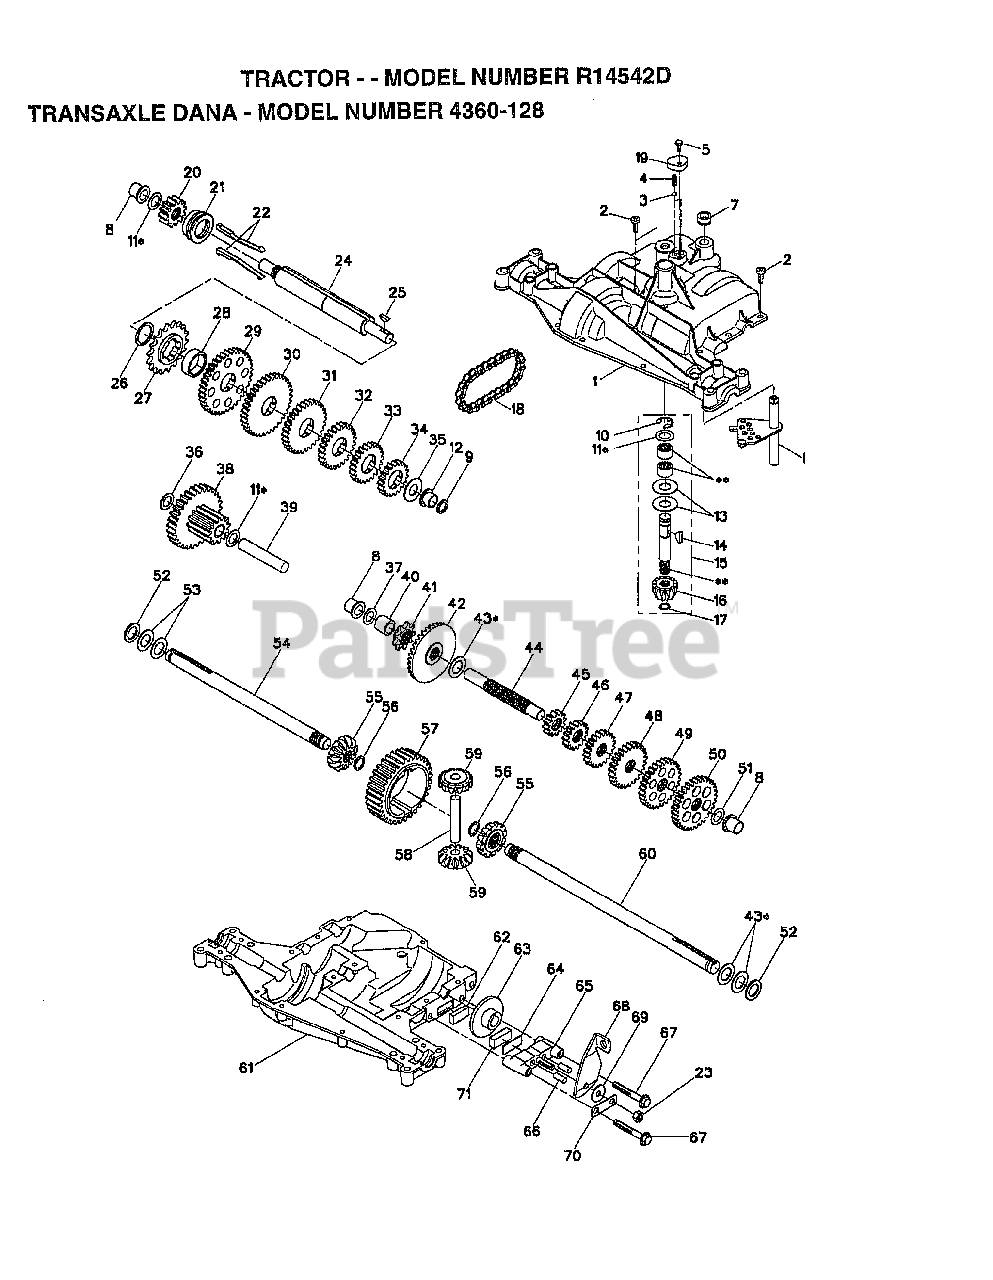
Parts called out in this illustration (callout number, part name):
1	HOUSING.UPPER(5305-P)
4	"SPRING, DETENT LT"
5	SCREW.TAPPING.1/4-20X.734
6	KIT SHIFTER ASM
9	SEAL.OIL.DAN.5508
10	RETAINING RING LT
11	ASM KIT SHIM 4689
12	BEARING.FLNG.5511
13	WASHER T
14	KEY WOODRUFF-DANA
15	INPUT SHAFT KIT 6250
16	PINION.BEVEL.12T(5620)
17	"RING,RETAINING LT"
18	"CHAIN,24 PTCH LT"
19	COVER.DETENT.(5584)
20	GEAR.SPUR.12T.(5627)
21	CLUTCH.COL.5467
22	ASM KIT CLTCH KEY
23	NUT.LOCK.5/16-24
24	SHAFT INTERM DANA
25	WOODRUFF KEY
26	"RING,RETAINING LT"
27	SPROCKET 18T T
28	SPACER YT
29	GEAR SPUR 37 TTH
30	GEAR SPUR 35 TTH
31	GEAR SPUR 30T
32	GEAR 25T LT
33	GEAR SPUR 22 TT
34	SPUR GEAR 19T
35	"WASHER, PLAIN LT"
36	WASHER 045
37	WASHER 031
38	ASSY.GEAR.6153 12T&30T
39	SHAFT IDLER
40	SPACER T
41	SPROCKET 9T LT
42	GEAR.BEVEL.36T(5621)
43	ASM KIT SHIM
44	SHAFT T
45	GEAR SPUR 12 TTH
47	GEAR SPUR 20T
48	"GEAR, SPUR 25T LT"
49	GEAR 28T T
50	"GEAR, SPUR 31T LT"
51	WASHER 060
52	NEOPRENE WASHER
53	WASHER 031
54	AXLE.LH(5528-1)
55	MITER 5270 12T.SPLINED
56	RING.RETAINING.(5270)
58	SHAFT T
59	MITER 5623.12T.IDLER
60	AXLE.RH.(5528-2) DANA
61	HOUSING.KIT (6088)
62	PUCK T
63	BRAKE DISC. T
64	SPACER LT
66	PIN T
67	SCREW.(5562) .5/16-18X2.35
69	WASHER LT
70	BRACKET, ANTI-ROTATION
71	PUCK T
